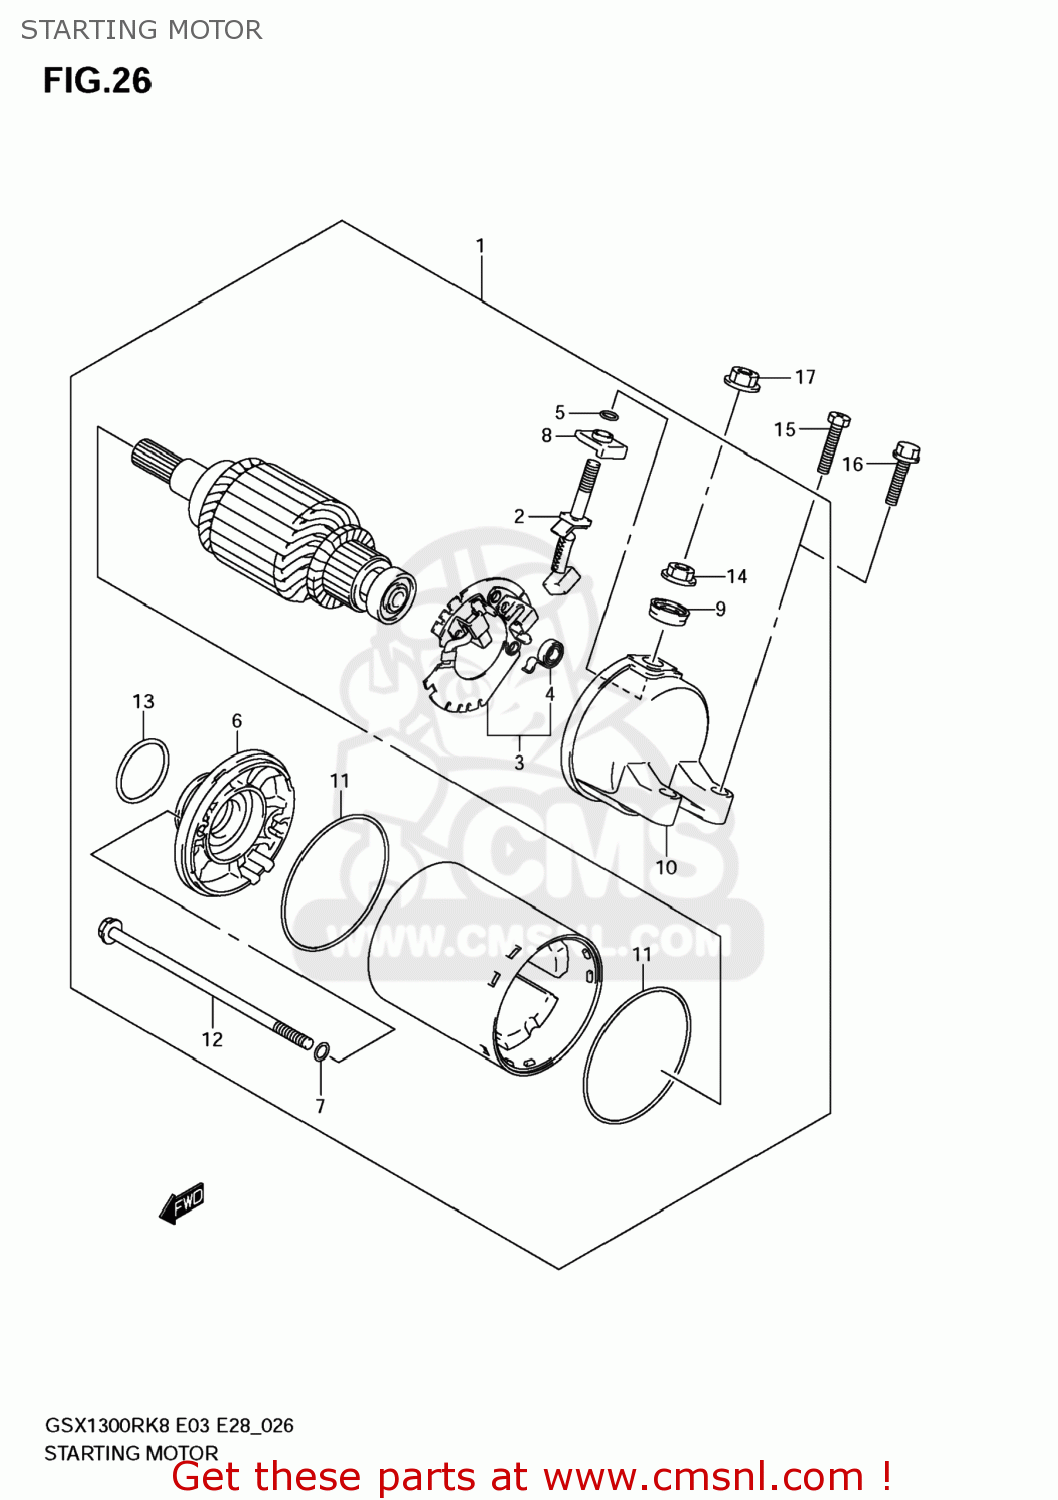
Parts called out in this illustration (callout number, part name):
1	MOTOR ASSY,STARTING
2	BRUSH SUB ASSY,STARTING MOTOR
3	HOLDER,BRUSH
4	SPRING
5	O RING
6	HOUSING ASSY,STARTING
7	O RING
8	BUSH,B
9	BUSHING
10	FRAME,STARTER END
11	O RING
12	BOLT
13	O RING(D:3,ID:24.5)
14	NUT
15	SCREW (6X25)
16	BOLT(6X25)
17	NUT
